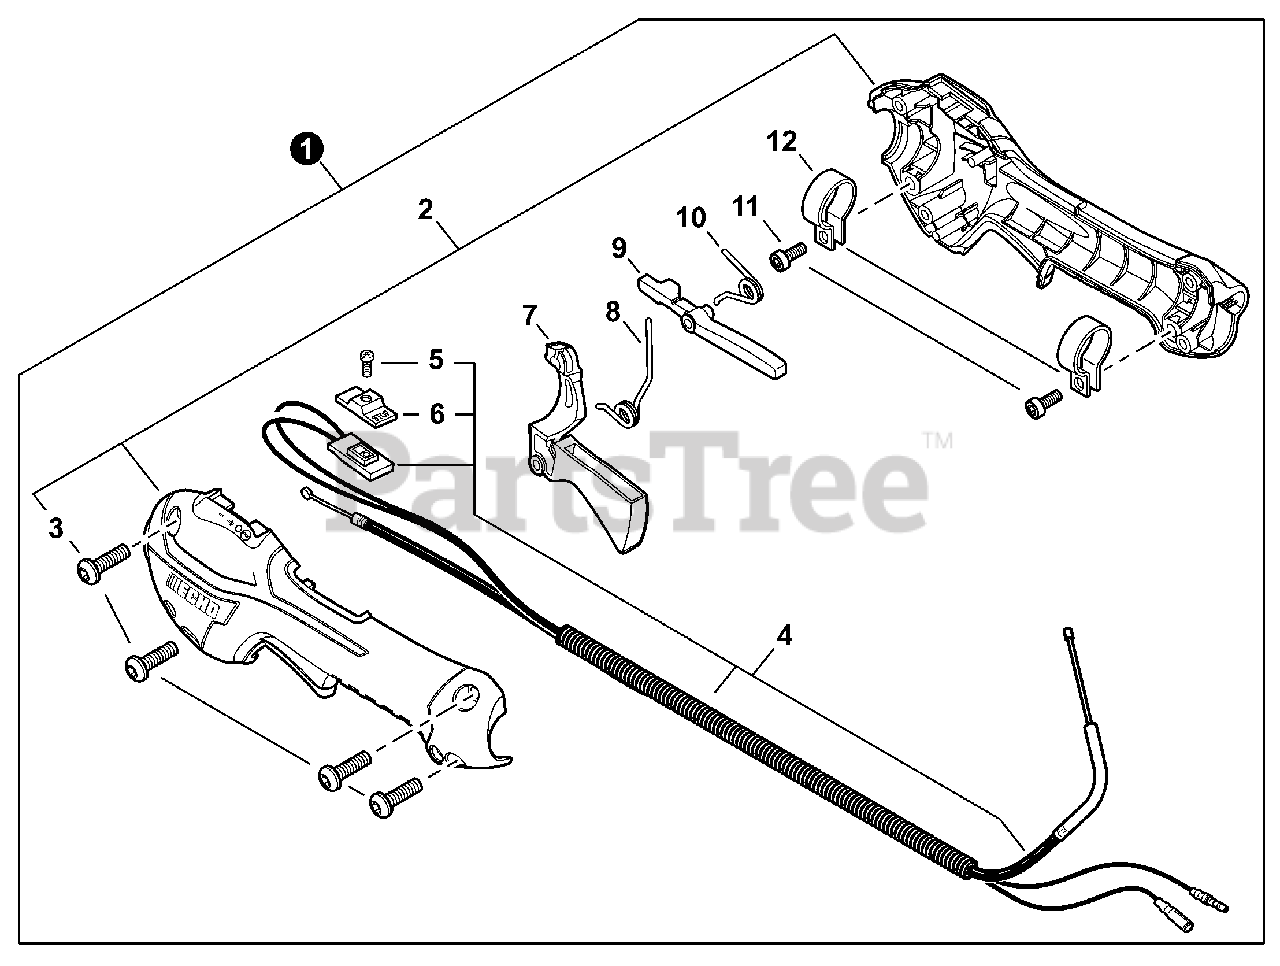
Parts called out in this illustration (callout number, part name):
1	CONTROL HANDLE ASSY
2	CONTROL HANDLE KIT
3	BOLT, TORX 5×16
4	CABLE ASSY, CONTROL
5	SCREW 3×10
6	KNOB, SWITCH - ORANGE
7	TRIGGER, THROTTLE
8	SPRING, TORSION
9	LEVER, THROTTLE LOCKOUT
10	SPRING, TORSION
11	BOLT, TORX 5×16
